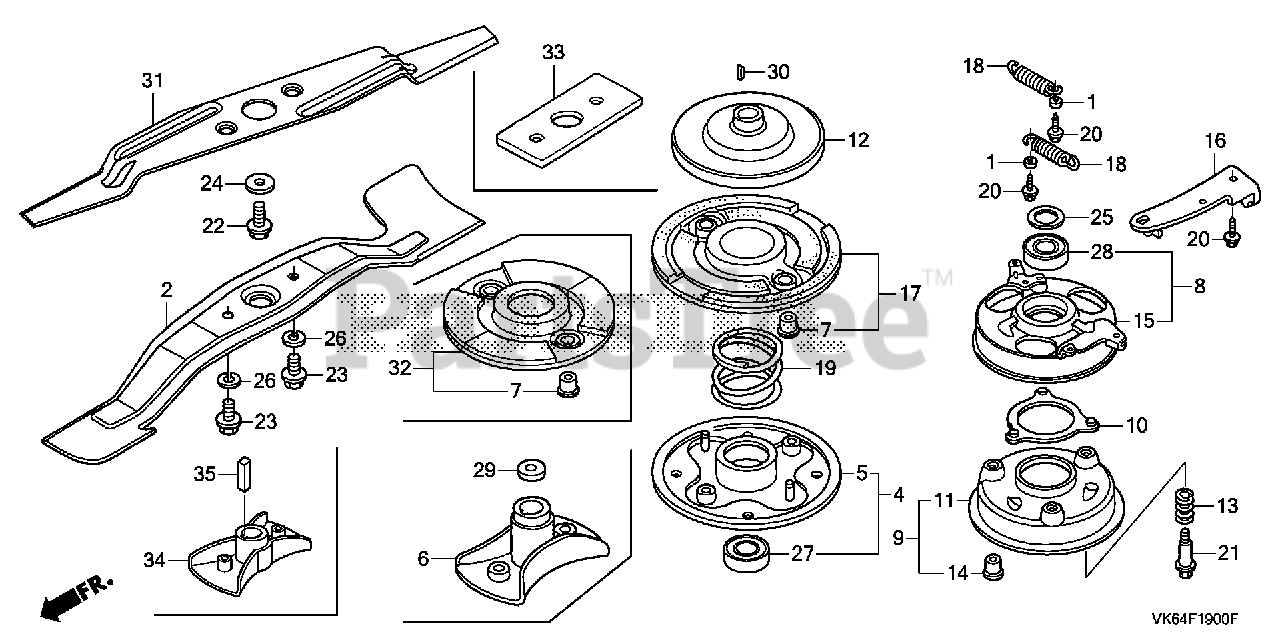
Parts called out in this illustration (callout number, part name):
1	COLLAR, FAN
2	BLADE, ROTARY
4	HOLDER ASSY., BLADE
5	HOLDER, BLADE
7	BUSH, BLADE HOLDER
8	PLATE ASSY., BALL CONTROL
10	RETAINER, BALL
11	DISK, BRAKE
12	DISK, DRIVE
13	SPRING, BRAKE HOLDER
14	BUSH, BRAKE HOLDER
15	PLATE, BALL CONTROL
16	PLATE, CABLE HOOK
17	DISK, DRIVEN
18	SPRING, CLUTCH RETURN (53.0MM)
19	SPRING, CLUTCH (36.6MM)
20	BOLT, FLANGE (6X14) (CT200)
21	BOLT, SPECIAL (6MM)
22	BOLT, HEX. (10X25)
23	BOLT, HEX. (10X20)
24	WASHER (10X30X3.5T)
25	WASHER, THRUST
26	WASHER, SPRING (10MM)
27	BEARING, RADIAL BALL (6204)
28	BEARING, RADIAL BALL (60/22)
30	KEY, WOODRUFF (16X15)
31	BLADE, ROTARY (UPPER)
32	DISK, DRIVEN
33	SPACER KIT, BLADE
